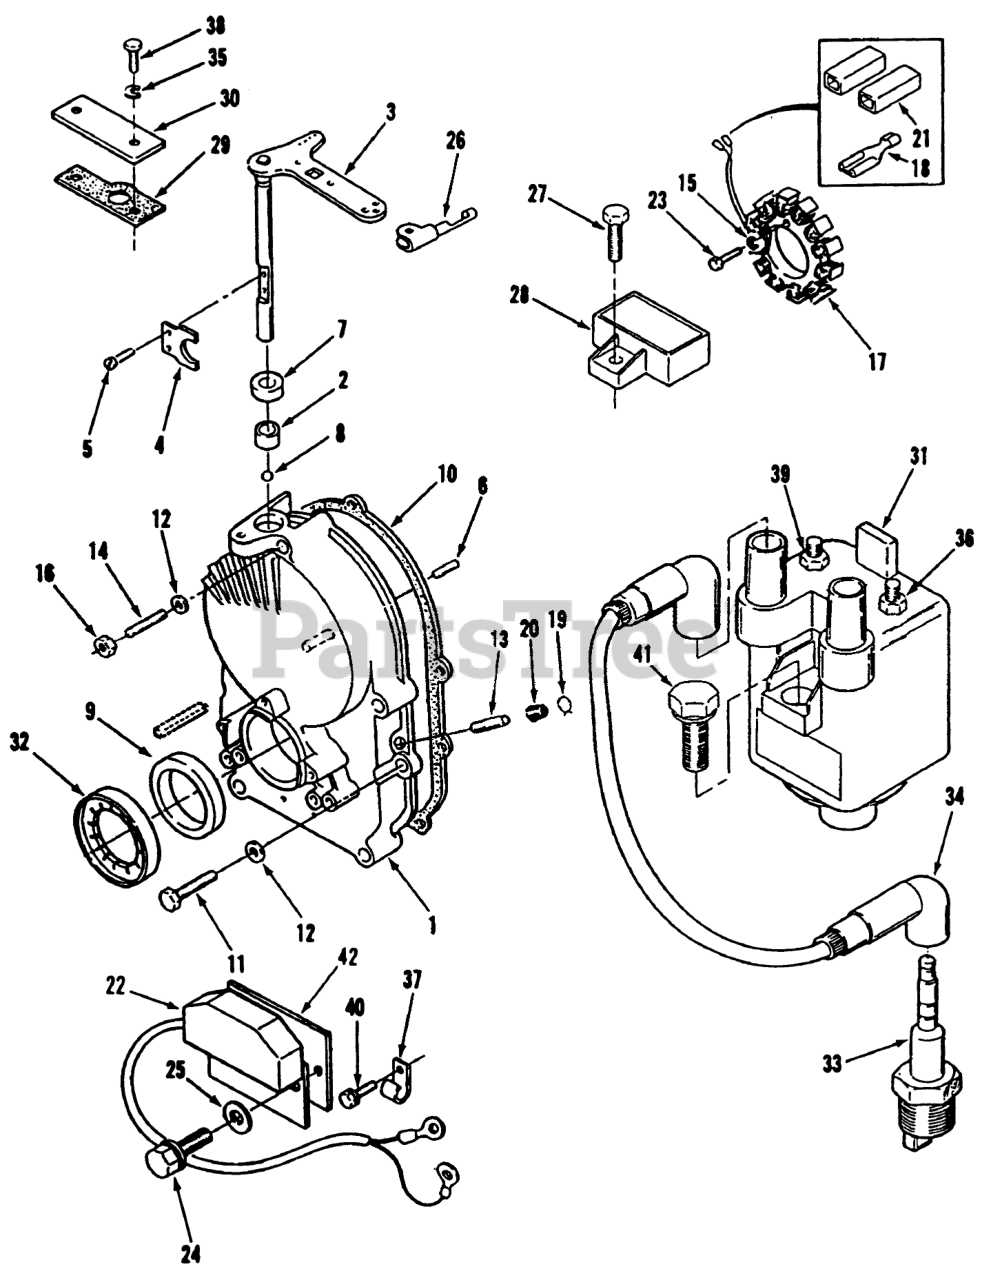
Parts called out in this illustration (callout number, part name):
1	Kit-Gearcase (Incl. Ref. #2-9, 13, 19, & 20)
2	BEARING
3	SHAFT AND ARM
5	SCREW-PAN HD
6	Washer
8	Bearing
10	Gasket
11	Bolt
12	WASHER
13	TUBE-PORT, VACUUM
14	Stud
15	WASHER-LOCK
16	Nut
17	Stator w/Terminals
18	Stator Leads Terminal
19	CLAMP
20	CAP-FUEL OUTLET
21	BODY-TERM. CONNECTOR KIT
22	Control-Ignition
23	Screw-HH
24	Bolt
25	WASHER-LOCK
27	Bolt
28	Regulator
29	Gasket-Plate
30	Plate
31	Coil-Ignition
32	Rotor
33	SPARK PLUG
34	WASHER-FLAT
35	WASHER-FLAT
36	Nut
37	Clip
38	SCREW - CAP HEX HEAD
39	Nut
40	Bolt
41	Bolt
42	Insulator
